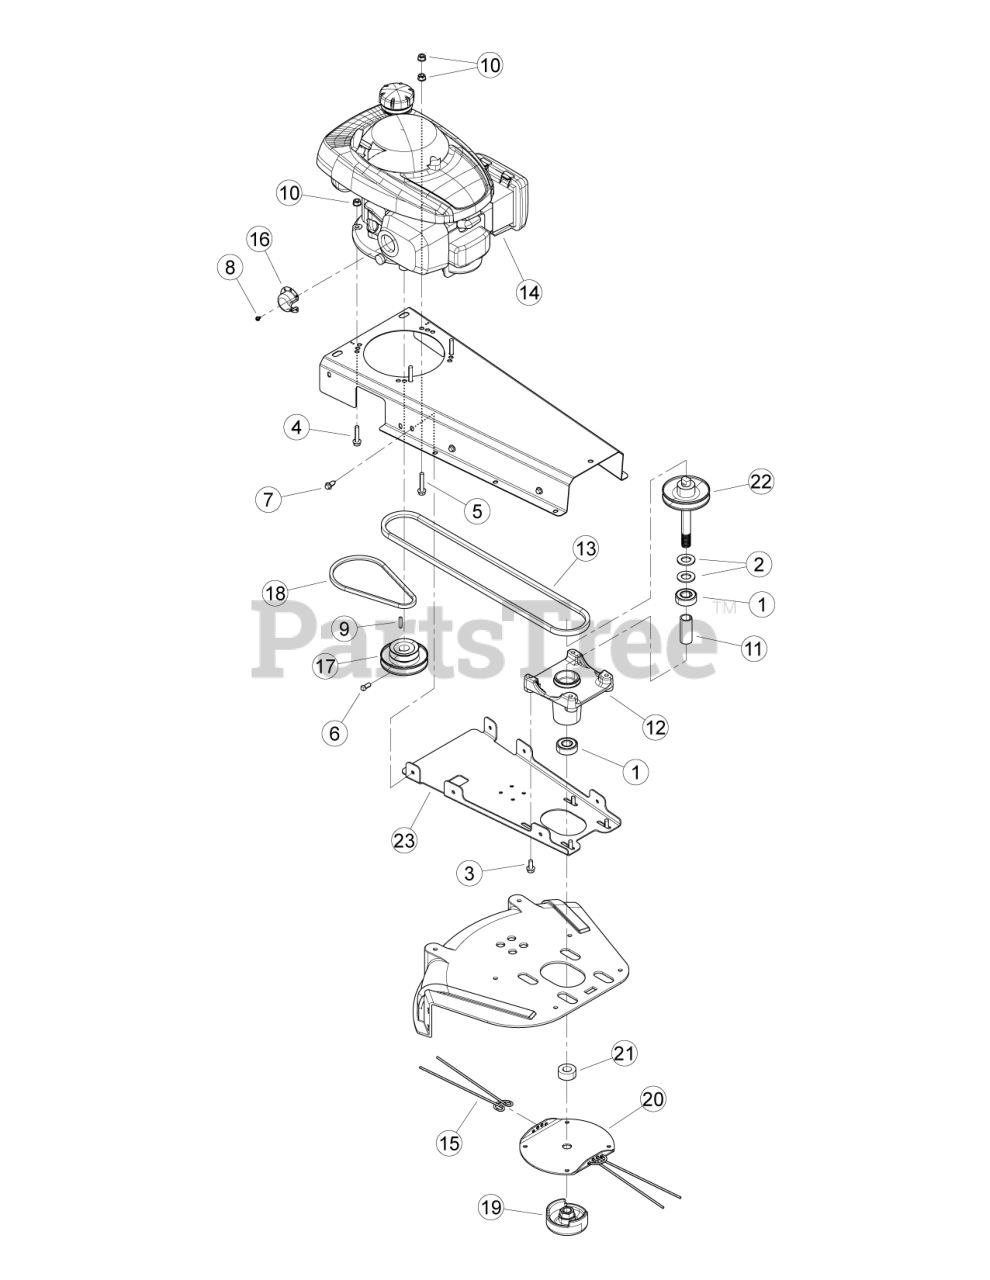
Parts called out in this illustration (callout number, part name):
1	BEARING, 3/4 BALL
2	WASHER, 3/4" SAE FLAT ZP
3	BOLT, 5/16 × 3/4 FLANGE NC
4	BOLT, 5/16 × 1-1/2 FLANGE NC
5	BOLT, 5/16 × 1-3/4 FLANGE NC
6	SCREW, 5/16-18 × 5/8 SQ HD SET
7	SCREW, 11/32-12 × 7/8 FLANGE T-AB
8	SCREW, 8-32 X 1/4 HEX THREAD CUTTING
9	KEY, 3/16" × 1.00" LG SQUARE
10	NUT, 5/16-18 NYLOCK FLANGE
11	SPACER, TRIMMER SPINDLE
12	CASTING, TRIMMER SPINDLE HUB
13	BELT, AX48
14	ENGINE, HONDA 160CC VERTICAL
15	STRING, 20" X .155 DIA. CROSS-FIRE
17	PULLEY, 4.0/2.5 X .875
18	BELT, 3L220
19	MOWBALL, CAST TRIMMER PAINTED
20	DISK, TRIMMER HEAD
21	SPACER, TRIMMER HEAD
22	WELDMENT, SPINDLE HW MODELS
23	PLATE, HWS SPINDLE CASTING MOUNT
